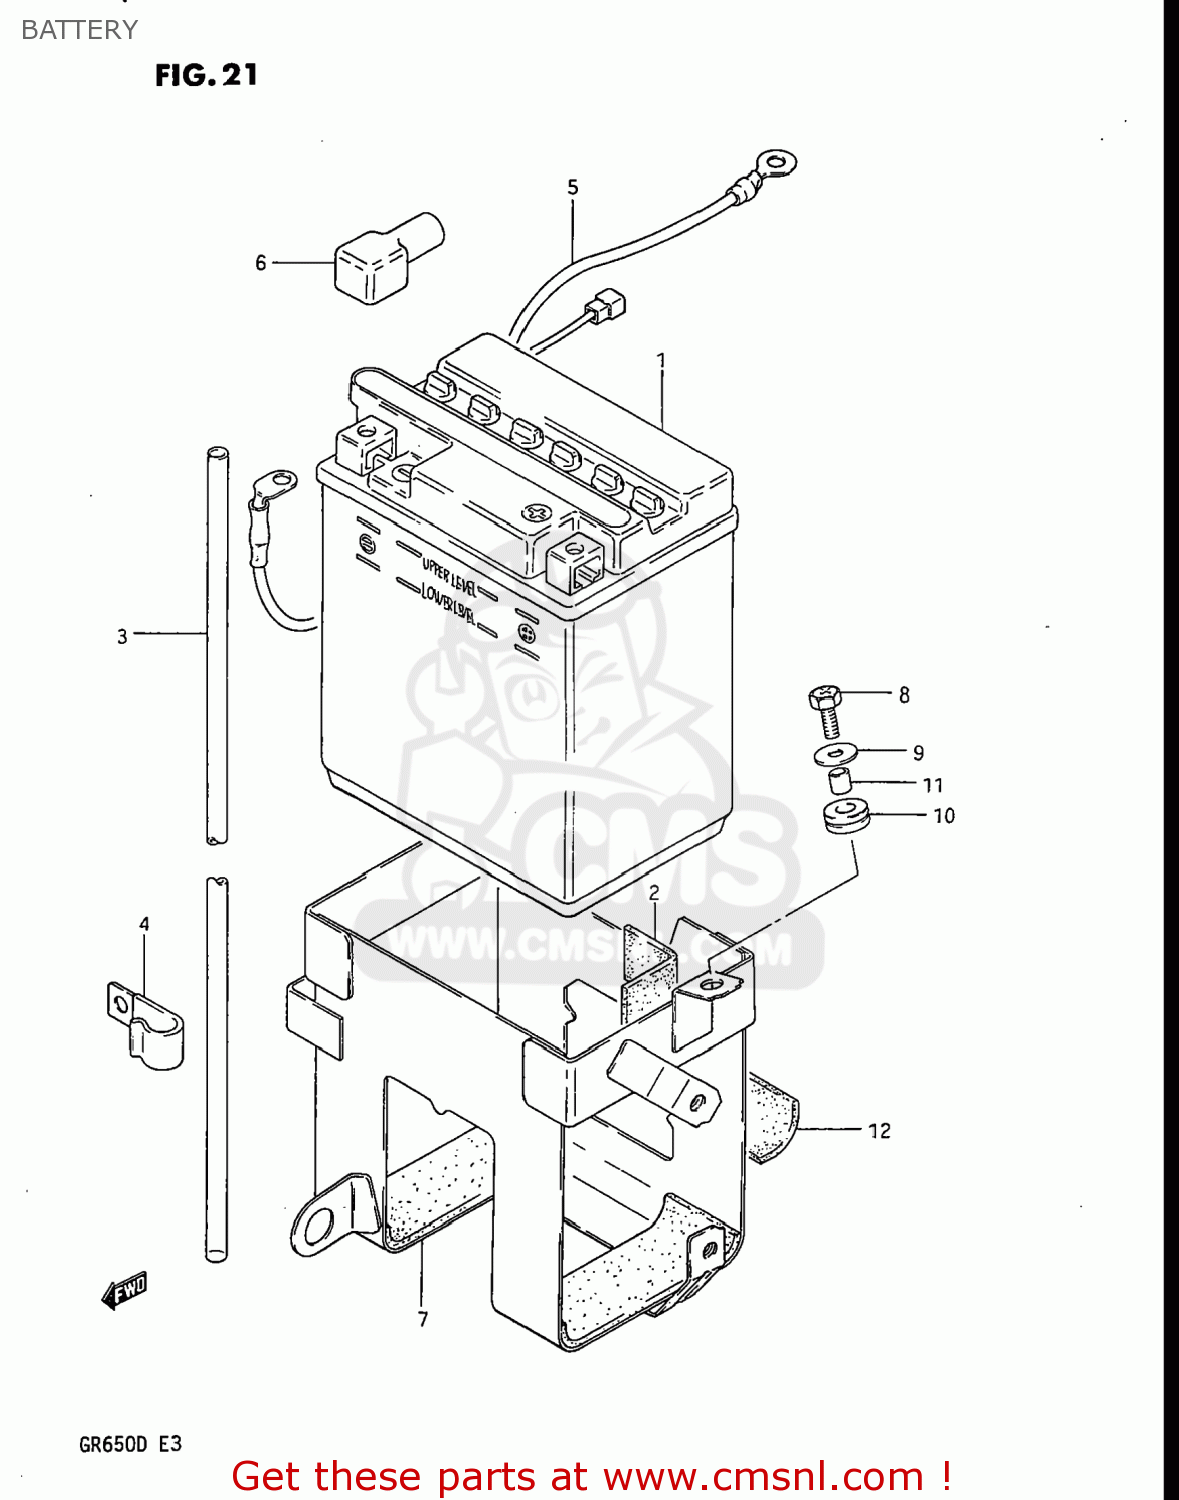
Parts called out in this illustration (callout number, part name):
1	BATTERY ASSY (12V)
2	PROTECTOR(170X95X3.0)
3	HOSE,BATTERY EXHAUST
4	CLAMP
5	WIRE,STARTER MOTOR LEAD
6	CAP,TERMINAL
7	HOLDER,BATTERY
8	SCREW
9	WASHER
10	CUSHION
11	SPACER(6.1X9X7.5)
12	CUSHION,BATTERY HOLDER
